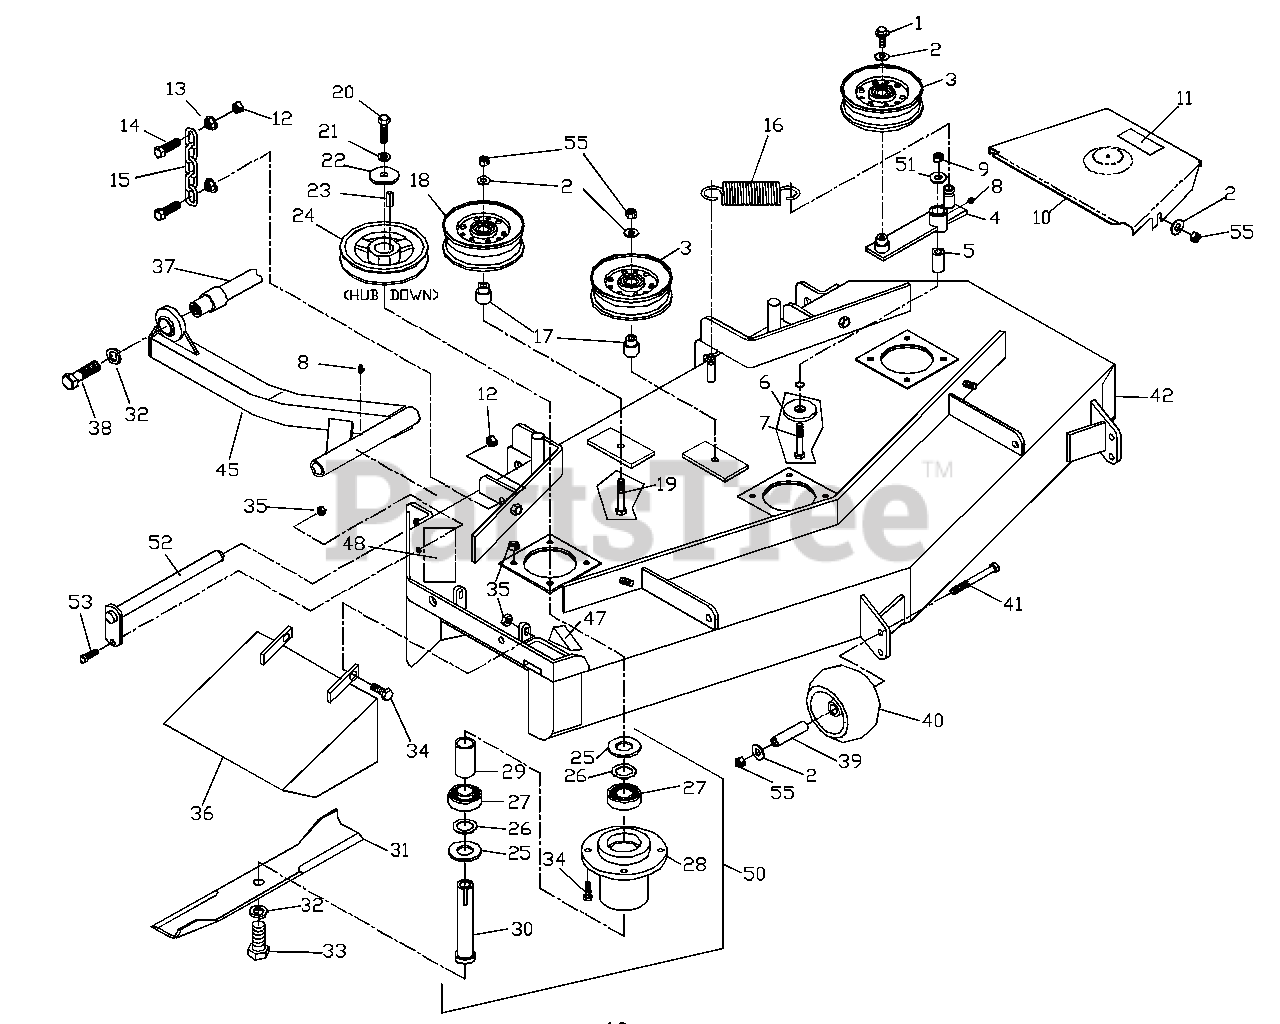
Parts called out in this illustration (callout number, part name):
1	HCS 3/8C X 1 SERRATED HEAD
2	WASHER 3/8 FLAT
3	IDLER PULLEY
5	PIVOT BUSHING
6	SUPPORT WASHER
7	HCS 1/2C X 3 1/4
8	ZERK
9	NUT 1/2C NYLOC
10	BELTSHIELD
11	DECAL, NO STEP
12	NUT 7/16C CENTERLOCK
13	7/16C WHIZ NUT
14	HCS 7/16C X 1 1/2
15	LIFT CHAIN
17	IDLER BUSHING
18	IDLER PULLEY(TALL)
19	HCS 3/8C X 2 1/2
20	HCS 7/16F X 1 1/2
21	LOCKWASHER 7/16
22	CRANKSHAFT WASHER
23	KEY 1/4 SQ. X 1 1/8
25	MACHINERY BUSHING 10 GA.
26	MACHINERY BUSHING 18 GA.
27	BEARING
31	16 1/4" BLADE
32	LOCKWASHER 5/8
33	HCS 5/8F X 1 1/4
34	HCS 5/16C X 1
35	NUT 5/16C CENTERLOCK
36	DEFLECTOR CHUTE
37	STRUT MOUNT WLDMT
38	HCS 5/8C X 2 GR.5
39	BUSHING
40	ANTI-SCALP ROLLER
41	HCS 3/8C X 3 1/2
42	DECK W/DECALS
45	STRUT WLDMT - RT
47	DECAL, CPSC
48	DECAL, DANGER
50	COMPLETE HOUSING
51	WASHER 1/2 FLAT
53	HCS 5/16C X 3/4
55	NUT 3/8C CENTERLOCK
